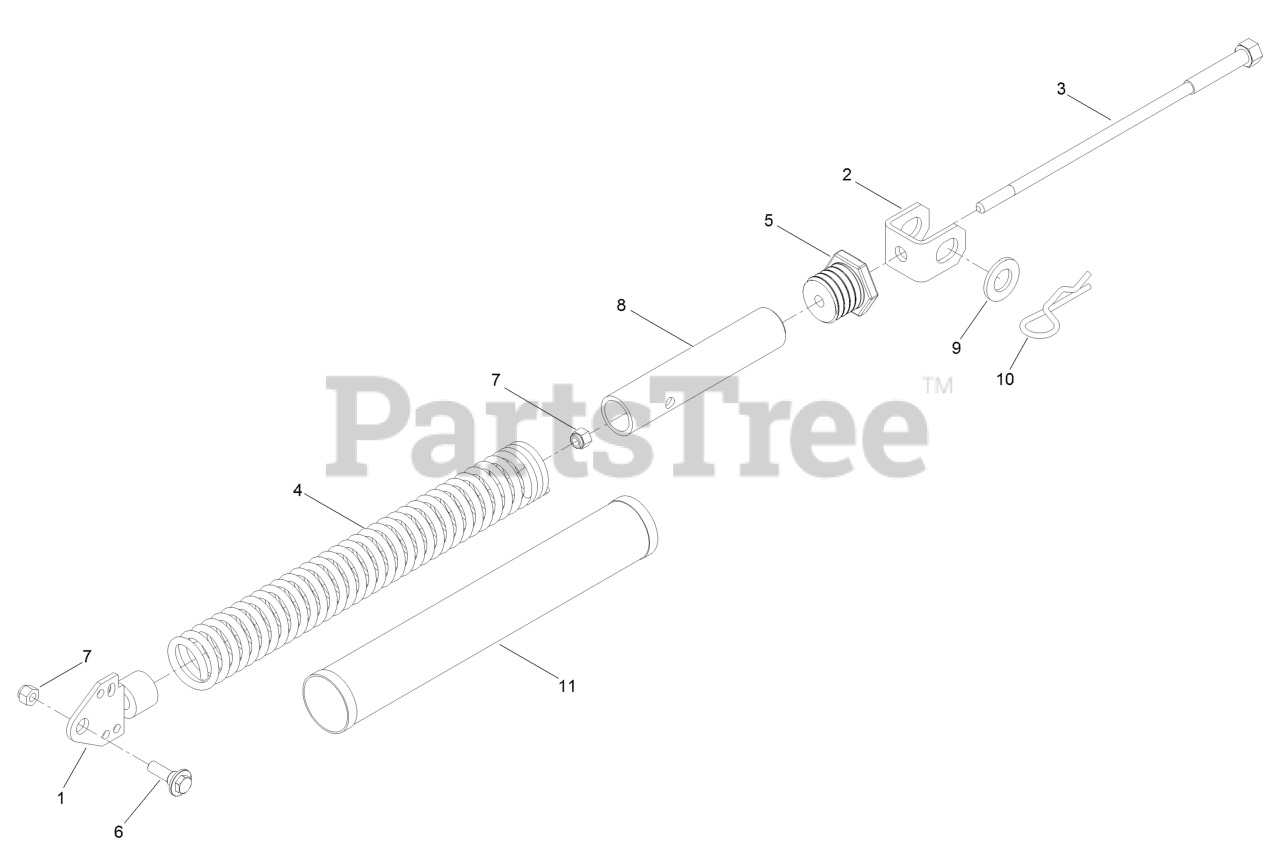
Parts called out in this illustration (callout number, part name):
1	TENSIONER-SPRING
2	MOUNT-LIFT ASSIST, DECK
3	SHAFT-ADJUSTMENT, SPRING
4	SPRING-EXTENSION
5	PLUG-ADJUSTER, SPRING
6	SCREW-SHOULDER, HWH
7	NUT-LOCK, NI
8	SPRING-TUBE
9	WASHER-FLAT
10	PIN-CUT HEIGHT
11	COVER-SPRING, DECK
